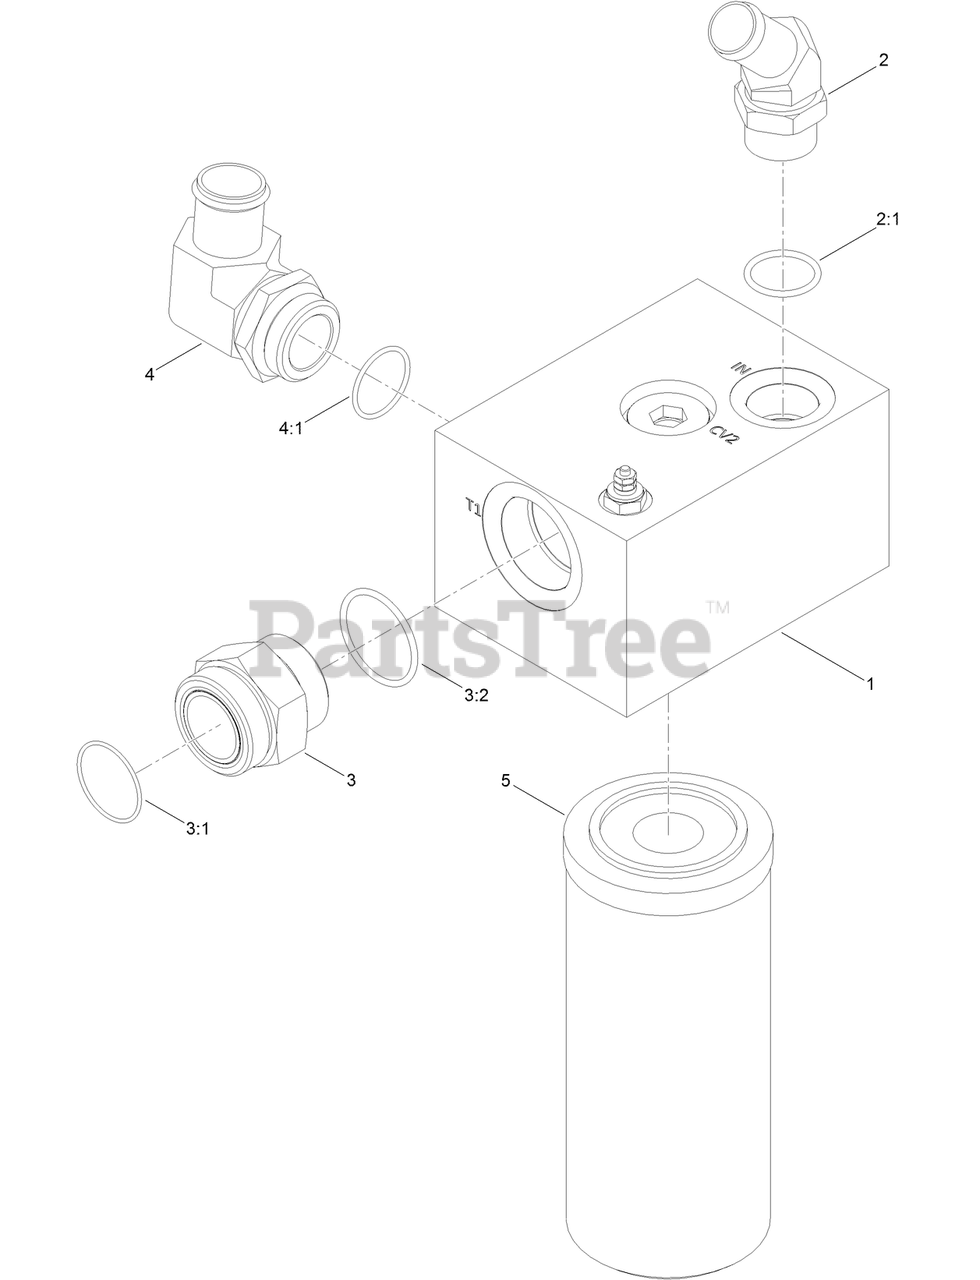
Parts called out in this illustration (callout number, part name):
1	RETURN MANIFOLD ASM
2	FITTING-ELBOW-45
2:1	O-RING
3	FITTING-STR
3:1	O RING
3:2	O-RING
4	FITTING-HYD 90 SPCL
4:1	O-RING
5	ELEMENT-FILTER
